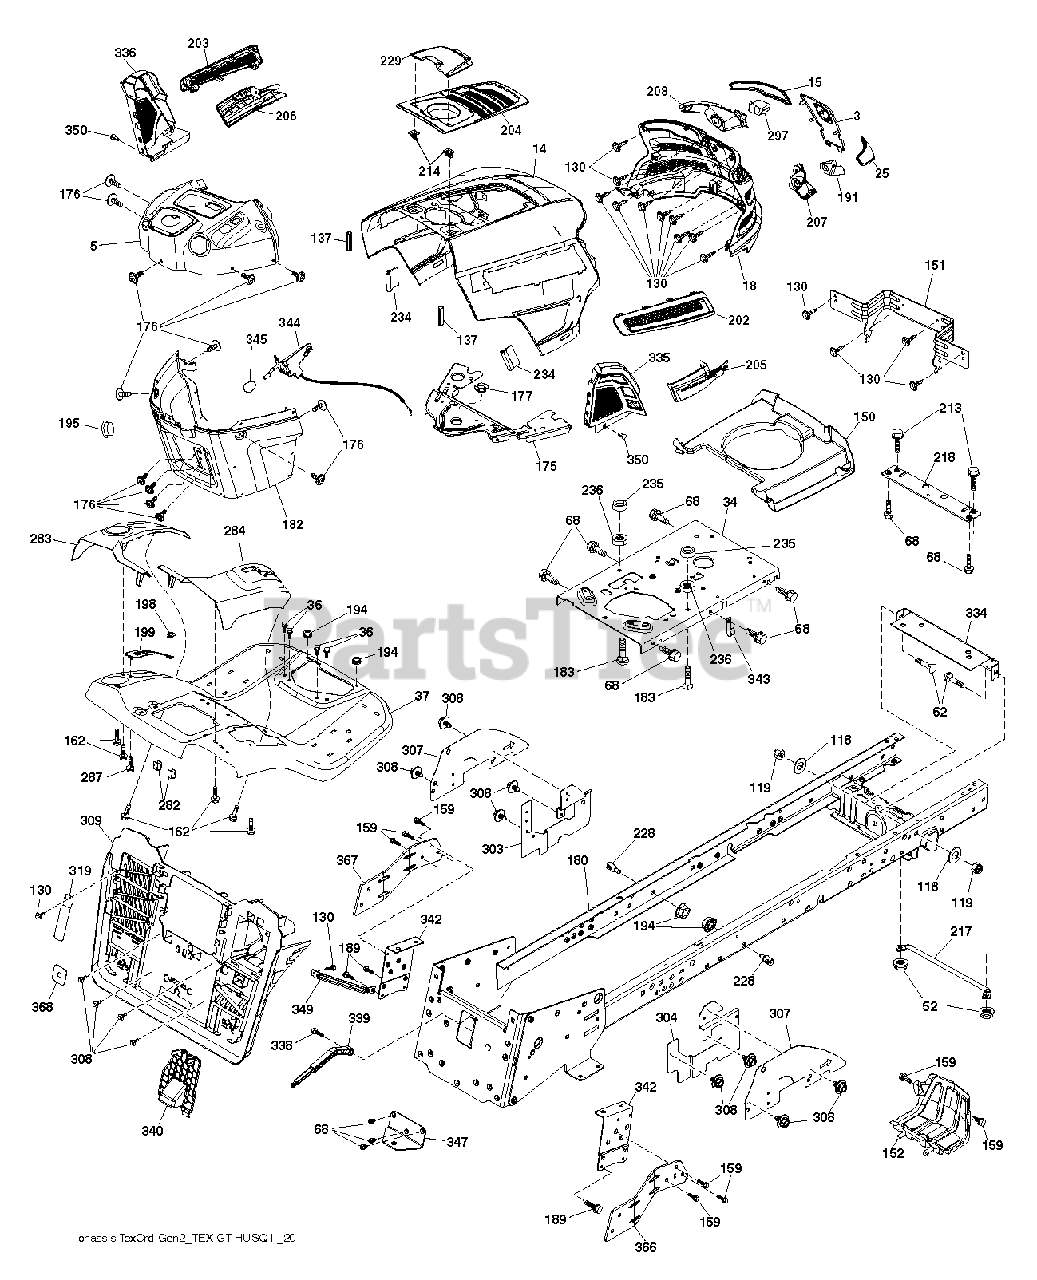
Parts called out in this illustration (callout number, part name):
3	APPLIQUE.SUBASM.GT.HUSQ.II
5	GT2.DASH.UPPER.W/BUMPERS
14	HOOD.ASM.HUSQVARNA.GT.TEX.ORAN
15	LED LIGHT.LH
18	GRILLE.SUBSTRATE.2011.
25	LENS.RH
34	PLATE.ENGINE.10GA.CRD.GENII
36	SCREW 5/16"
37	FENDER.TEX.SRD.CRD.FRN.GUARDS
52	LOCKNUT
62	BOLT D
68	SCREW LT
118	WASHER
130	SCREW.#10 X 0.750.BOS
137	BUMPER DASH
150	AIR.DUCT.GTV.BLACK
151	BRACKET.PIVOT.HOOD.GT.HUSQ.II
152	SHIELD.BROWNING.PNT.GT.V2
159	SCREW, 3/8-16X3/4
162	SCREW.HI-LO.CONSOLE
175	PLATE.CROSSMEMBER.HUSQ
176	SCREW.#10-24X5/8.RN.QU
177	BUSHING, STEERING
180	WELDMENT.CHASSIS.TEX.CRD.GEN.2
182	DASH DASH LOWER
183	BOLT.5/16-18X1-1/4 FULL THD
189	SCREW
191	INSERT INFLECT.RH
194	NUT LOCK HEX FLANGE 5/16-18
195	PLUG.HOLE.DASH.LOWER.12V.BLK
198	INDICATOR.DECK.LIFT.RED
199	PLATE DECK LIFT
202	VENT.SIDE.RH.GT.HUSQ.II.
203	VENT.SIDE.LH.GT.HUSQ.II.498
204	VENT.TOP.EXTERNAL.FILL.GT2.GRE
205	SIDE.TRIM.RH.GT.HUSQ.II
206	SIDE.TRIM.LH.GT.HUSQ.II.GRAY
207	LIGHT.BEZEL. RH
208	LIGHT.BEZEL.LH
213	BOLT
214	CLIP.RETAINER.TINNER.
217	ROD.PIVOT.HOOD
218	X-PIECE.HOOD.STOP.NON/
228	STUD.FASTNER.W/ANTI-ROTATE
229	LID.EXT.FILL.GT.HUSQ2.BLACK
234	BUMPER.HOOD.TEX.HUSQVARNA
235	SPACER FENDER
236	NUT.CENTERLOCK.5/16-
282	CLIP.RETAINER.CONSOLE.LT.HUSQ
283	CONSOLE.DECKLIFT.CRDII.498
284	CONSOLE.PEDAL.HYDRO
287	SCREW 1/4X20
297	INSERT REFECT LH
303	SHIELD.LWR.LH.LT.30"CRDSRD.PNT
304	SHIELD.LWR.RH.LT30DECK.PNT.BLK
307	SHIELD.UPPER.CRD.SRD.ISO
308	BOLT, 5/16-18 X 1 3/4
309	BACKPLATE.ASM.CRDII.ANTIROTAT
319	LEVER.BAG.CRDII.ANTIROTATION
334	BRACKET.ENGINE
335	COVER.LOWER.DASH.RH.BLACK
336	COVER-LH.LOWER.DASH.GT2.BLACK
338	BOLT BOLT SHOULDER
339	LEVER LEVER BAGGER
340	BATTERY.DOOR.TEX.CRD.GEN.2,1
342	SUPPORT SUPPORT FENDER
343	CLIP CLIP
344	CONTROL.EZ.MULCH.TEX/CRD
345	RP KNOB.OVAL.TAPERED.3/8-16BLK
347	HITCH HITCH TOW TEX CRD GEN 2
349	BRACKET.SUPPORT.LRVB/CRD
350	CLIP.X-MAS.TREE
366	BRACKET.RH.FRONT.BAGGER.BLACK
367	BRACKET.LH.FRONT.BAGGER.BLACK
368	FULL.LEVER.BAGGER.TEX.CRD
